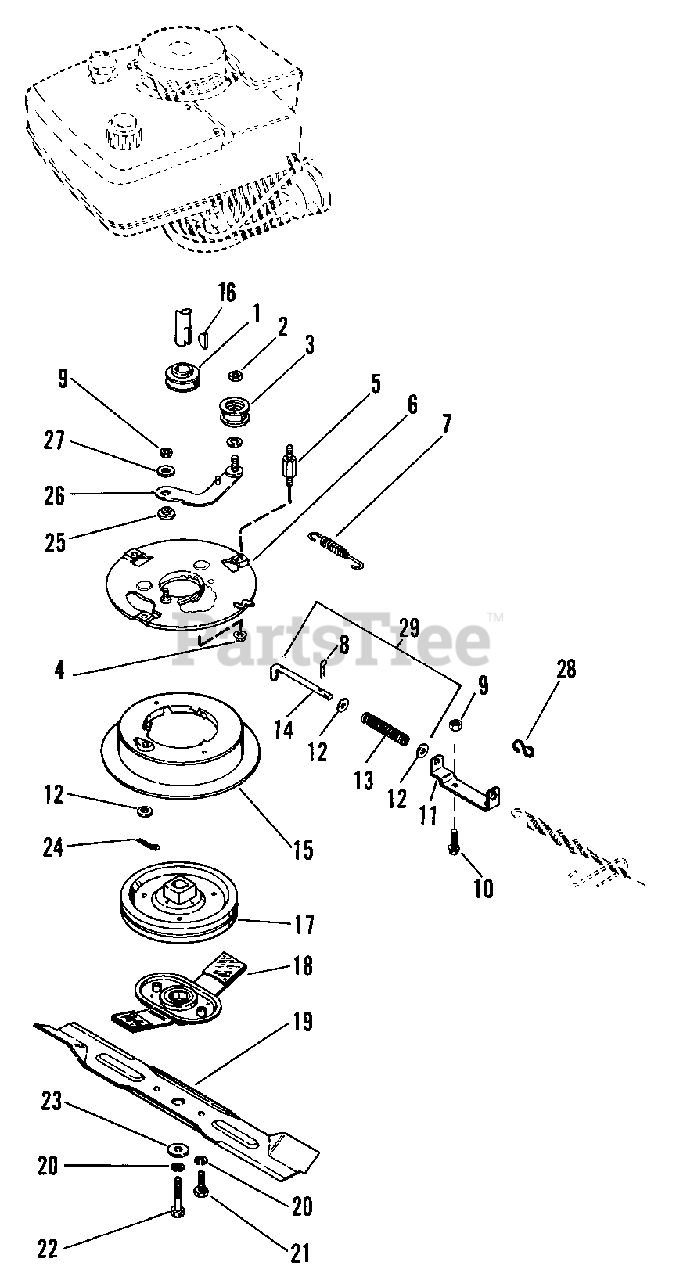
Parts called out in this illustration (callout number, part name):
1	SHEAVE,DRIVE
2	NUT-LK-CTR .375-16 GR A PL
3	IDLER-FLAT 1.50 X .39 CLARK
4	NUT-FLG. .312-18 PL
5	HEX STUD-BBC
6	ASM - RAMP
7	SG-TENS .051X.60X2.25 WLD 7.0
8	PIN-HAIR INT .06X.18X.77
9	NUT-LK-CTR .250-20 PL
10	BLT-RDHDSQNK .25-20X.50 SHT PL
11	CABLE MTG. BRKT
11	CABLE MOUNT, BBC
12	WSHR-FL-STL .260X.500X.060 PL
12	WSHR-FL-STL .328X.555X.06 PL
13	SG-COMP .062X.422X8.50 WLD 24
13	SG-COMP .080X.550X8.50 WLD38
14	ROD-RETURN
14	ROD,RETURN BBC
15	ACTUATOR-BRAKE
15	ACTUATOR,BRAKE
16	KEY-WDRF .156X.625X.25 SAE 6
17	BBC FLYWHEEL
18	BBC LEAF SPRING AND BEARING AS
19	BLADE, 21" MOWER
20	WSHR-LK .375X.115 HVY PL
21	BLT-HEX .38-24X1.25 PL GR5
22	BLT-HEX .38-24X2.50 GR5
23	WSHR-FL-STL .382X1.25X.134 PL
24	@PIN-CTR .07X.50 EXTPRSQCT YZC
25	BSHG-FLG .325X.498X.265X.88
26	IDLER ARM WELDMENT BBC
27	WSHR-FL-STL .328X1.0X.094 PL
29	ROD RETURN ASSEM.
